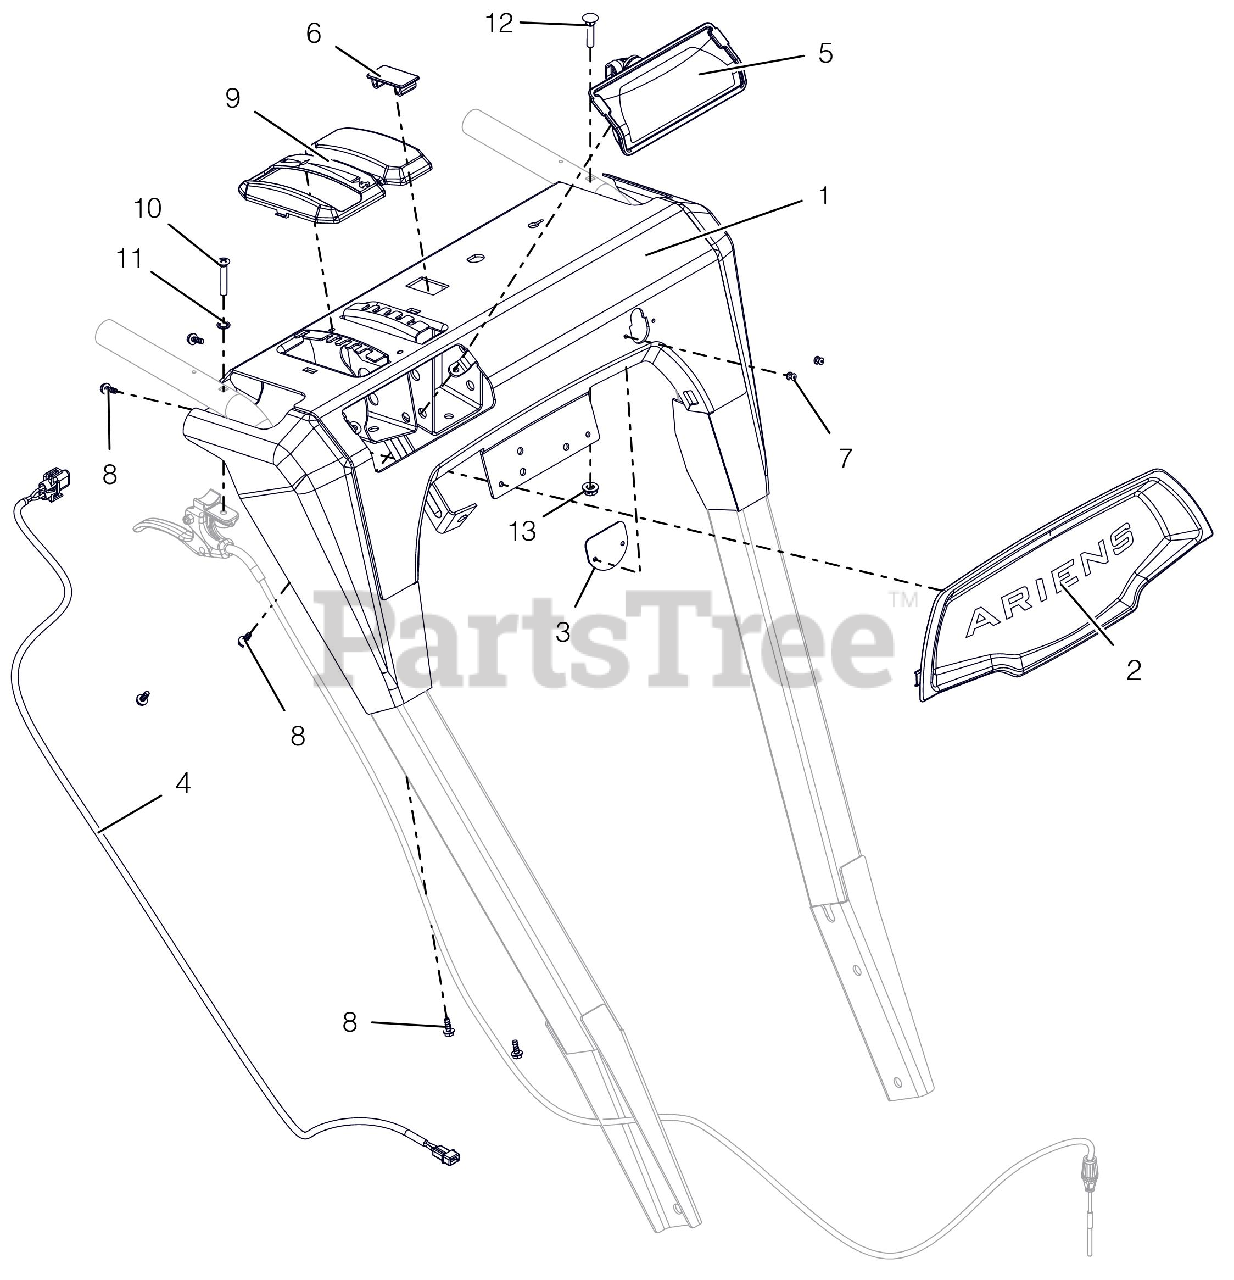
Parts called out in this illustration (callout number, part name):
1	PANEL, DASH - W/CTR DECAL
2	BEZEL, DASH - ARIENS LG DASH
3	COVER, DASH BRKT, BRUSH
4	HARNESS, LIGHT - DELUXE
5	HEADLIGHT ASY, HOLO 15W 2 SHOT
6	PLUG,DASH PANEL
7	RVT-POP #43 .125X.313 STL ZINC
8	SCR-TAP #10X.50 BOSS INDHXHD
9	BEZEL, SHIFT - FRICTION BRUSH
10	SCR-MCH .25-20X1.50 OVAL HD
11	WSHR-LK-INT .250 TH TYA
12	BLT-RDHDXLSQNK.25-20X1.25 G5ZC
13	@NUT-LK-CTR-FLG .25-20 YWZC
